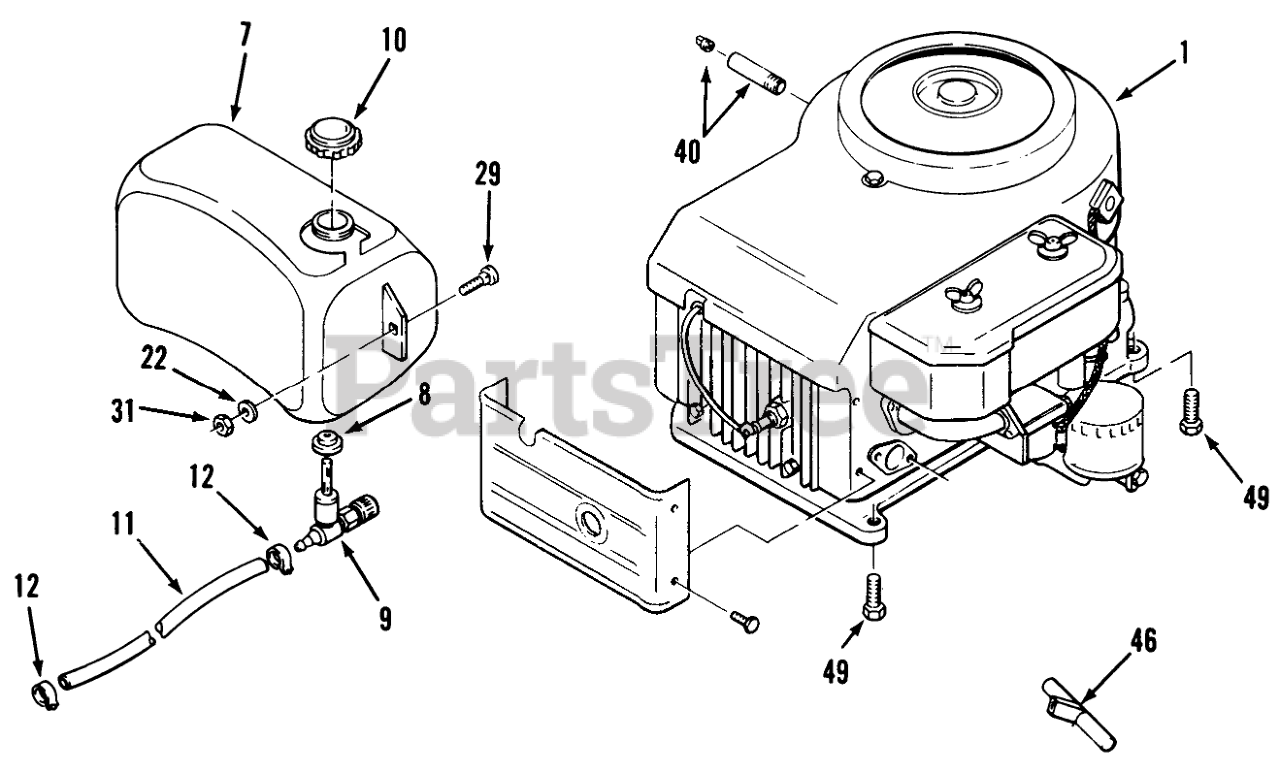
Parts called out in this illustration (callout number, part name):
1	Engine-12HP Kawasaki (Model No. FB460V Type CS26)
5	THROTTLE-CONTROL
7	Fuel Tank Assembly (Incl. Ref. #8 & 9)
8	BUSHING
9	VALVE-FUEL
10	CAP GAS
11	HOSE-FUEL LINE 17.62
12	CLAMP-HOSE
27	Screw
28	Nut
29	BOLT-CARR
31	NUT-LOCK, NI
40	Pipe
46	KNOB-CONTROL
49	Screw
